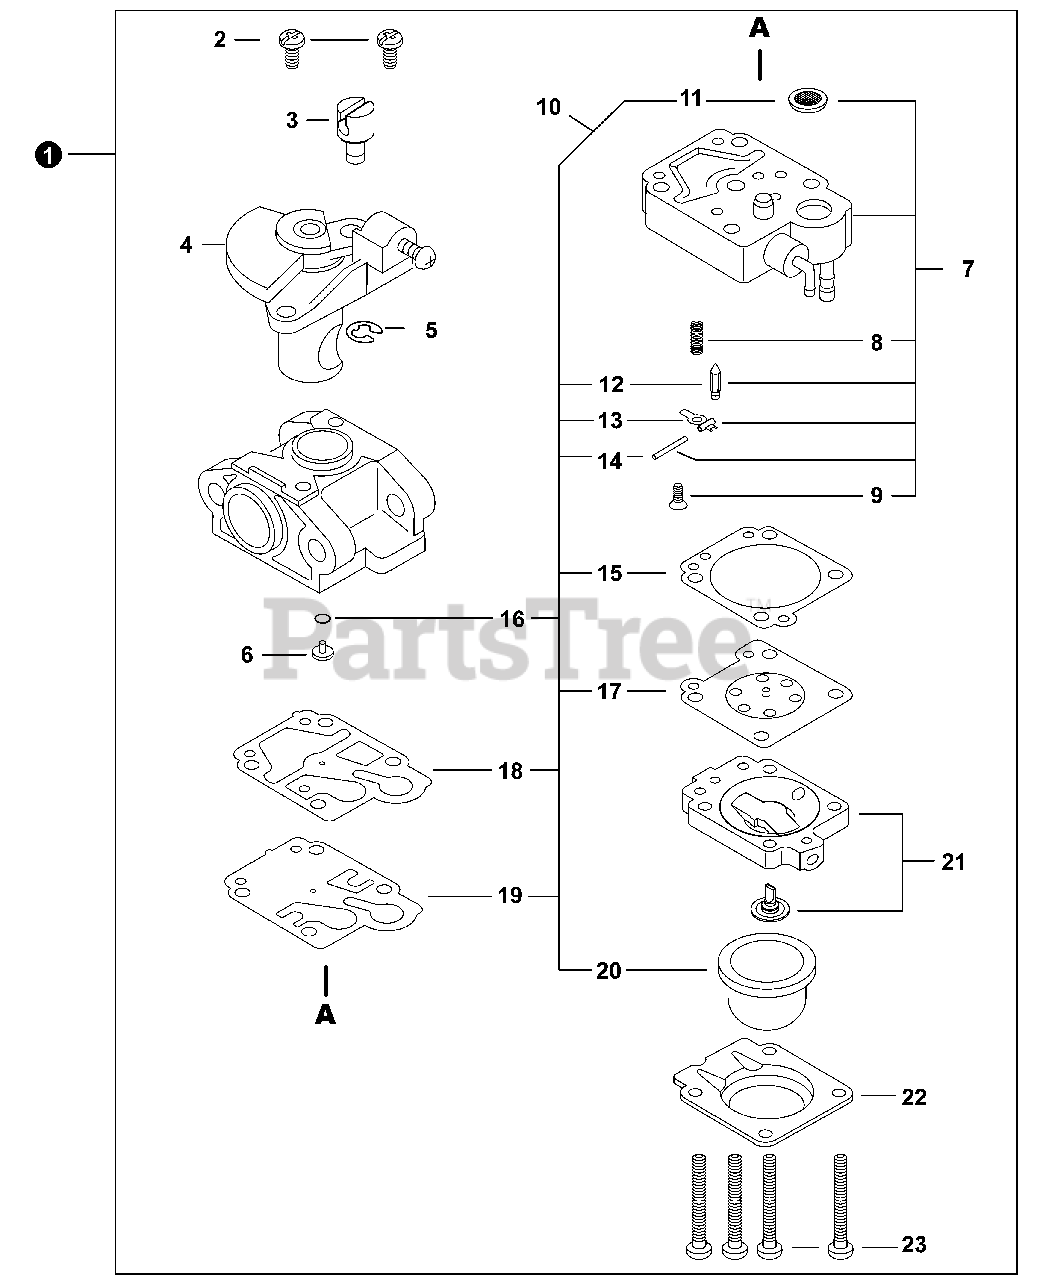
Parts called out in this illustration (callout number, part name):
1	CARBURETOR - WYL-170
2	SCREW, THROTTLE COLLAR
4	VALVE ASSY, THROTTLE
6	JET, MAIN #37
7	BODY ASSY, PUMP
8	SPRING, METERING LEVER
10	REPAIR KIT, CARBURETOR
11	SCREEN, FUEL INLET
12	VALVE, INLET NEEDLE
13	LEVER, METERING
14	PIN, METERING LEVER
15	GASKET, METERING DIAPHRAGM
17	DIAPHRAGM, METERING
18	GASKET, FUEL PUMP
19	DIAPHRAGM, FUEL PUMP
20	BULB, PURGE
21	BODY ASSY, PURGE
22	RETAINER, PURGE BULB
